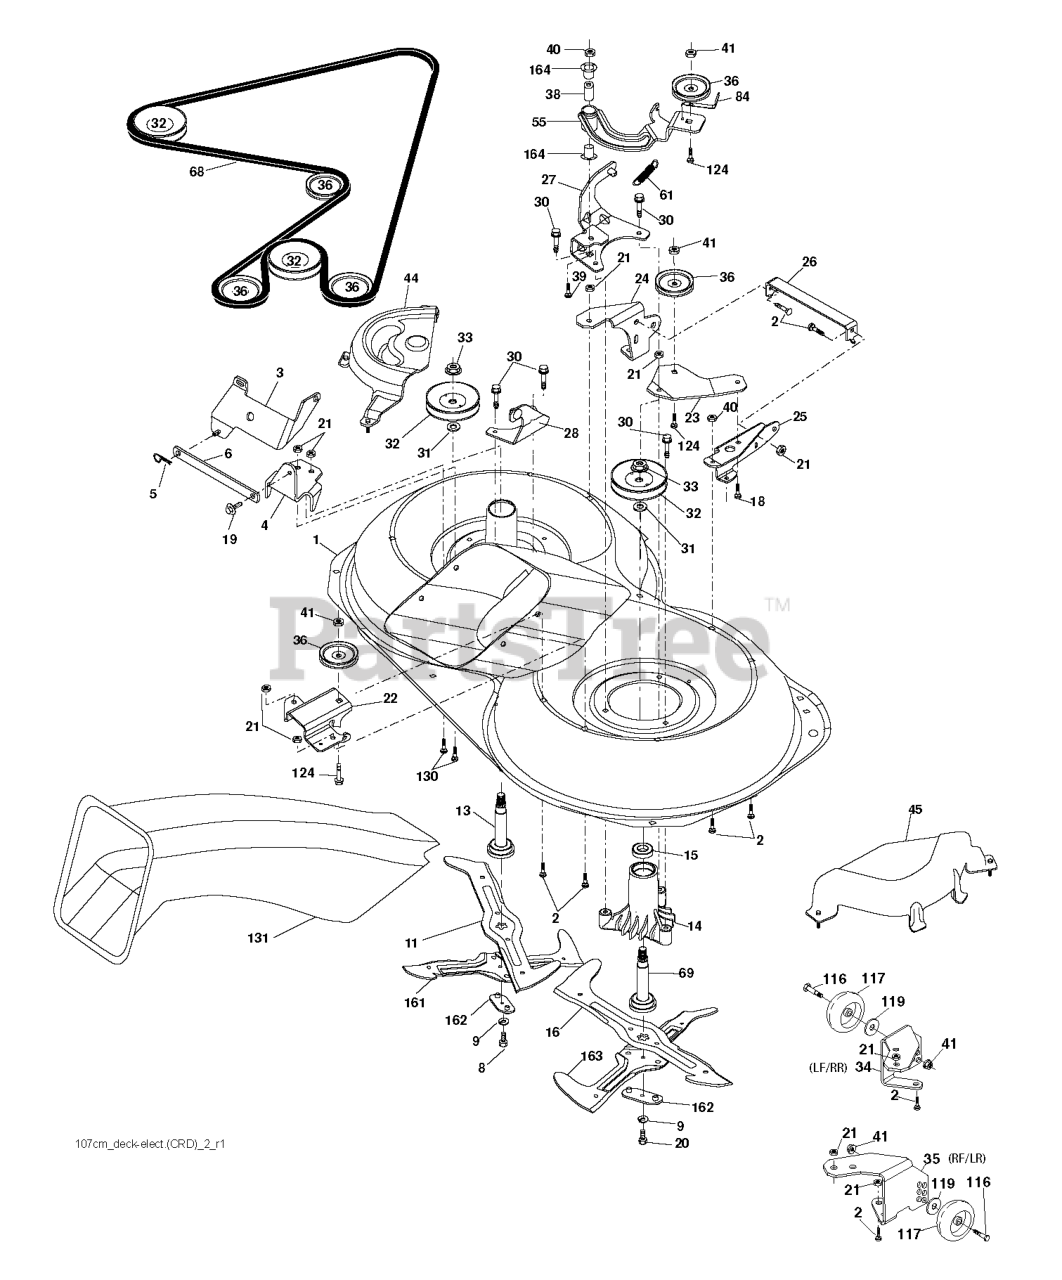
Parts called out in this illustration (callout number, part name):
1	Housing Asm. Mower 107 CRD
2	RP BOLT 5/16-18 X3/4 ZN/YEL GR
3	BRACKET.ASM.BAR.SWAY.CHASS
5	RETAINER-SPRNG RB
6	BAR.SWAY.92.CRD
8	BOLT.3/8-24X1.25 GR8
9	LOCKWASHER
11	BLADE.3N1.LH.CRD
13	SHAFT ASM VENT
14	HOUSING.MANDREL.VENTED (MACHD)
16	BLADE.3N1.RH.CRD
19	BOLT SHD 5/16-18
20	BOLT.3/8-24X1.25GR8. LHTHRD
21	LOCKNUT
22	BRACKET.IDLER.RR.107.CRD
24	BRACKET
25	BRACKET RF
26	SUPPORT
28	BRACKET
30	SCREW, WASHER HEAD
31	WASHER.SPACER.MANDREL
32	PULLEY.MANDREL.4.80 PD.2006
33	NUT.FLANGE.LOCK.TOP
34	BRACKET
35	BRACKET
36	PULLEY.IDLER.4.25
41	NUT LOCK FLG 3/8-16 UNC
45	COVER.MANDREL.RH.CRD
46	SCREW.1/4-20X5/8
55	ARM.IDLER.107.CRD
61	SPRING
68	HEX-BELT 107 MOWER
69	SHAFT.ASM.W/LWR.BRG.RH.THREAD
84	KEEPER, BELT IDLER
116	BOLT.SHOULDER.3/8-16X3-5/8.
117	RP WHEEL. GUAGE RALLY
118	NUT LOCK FLG 3/8-16 UNC
119	WASHER
124	BOLT.3/8-16X1.50
130	BOLT.CARR.SQNK.5/16-18UNC.X3/4
131	CHUTE BAGGER
163	BLADE.CROSS.RH.CRD.107
164	BRNG T
